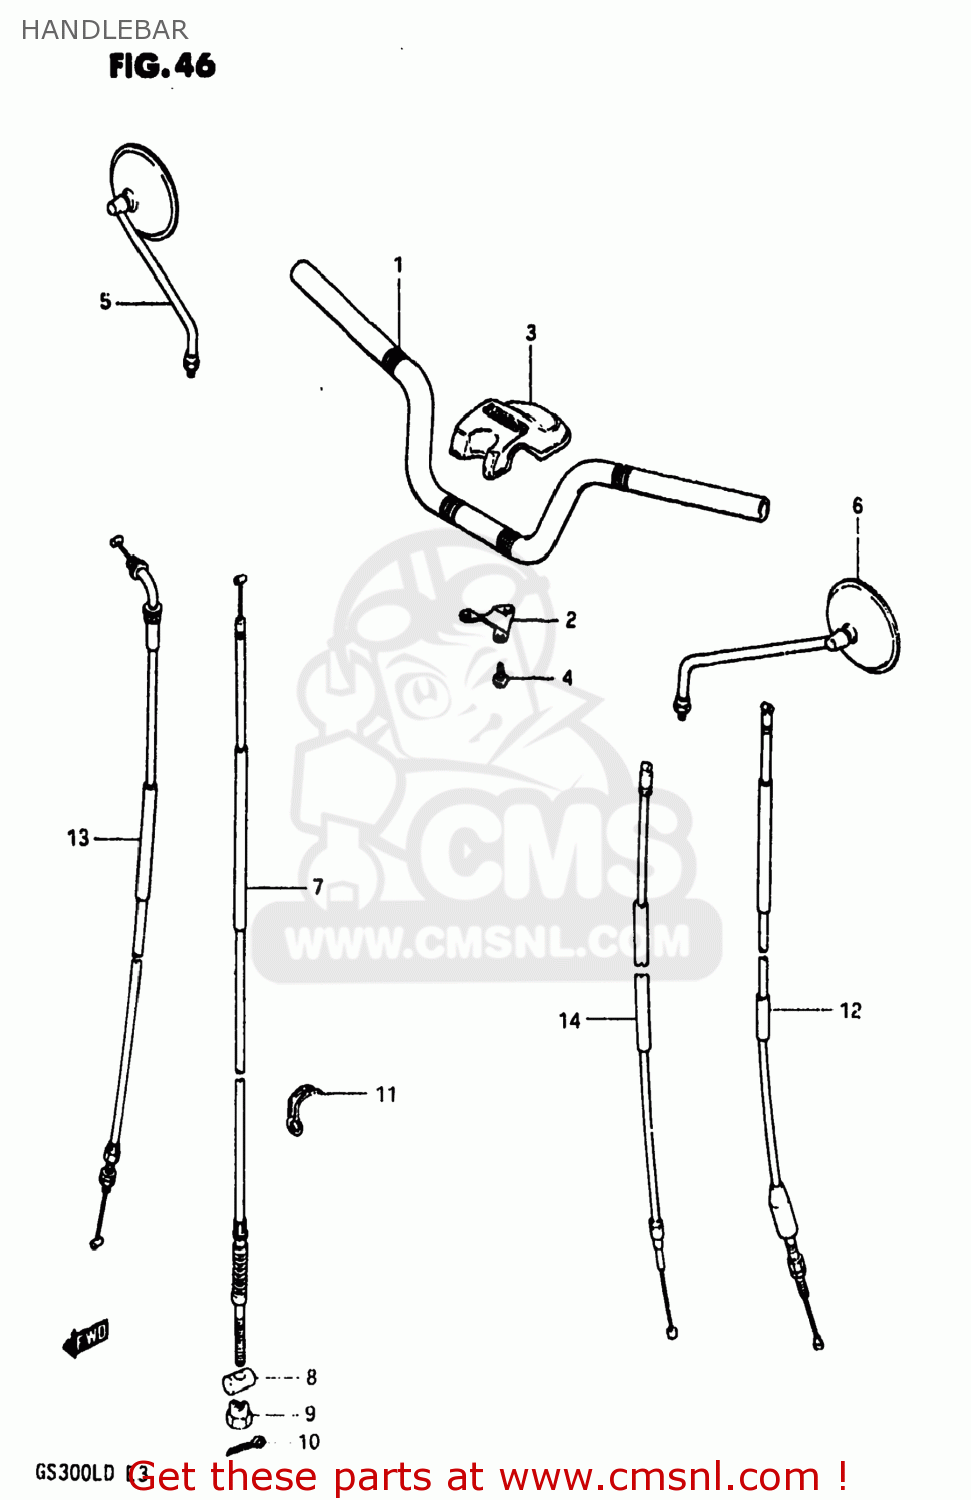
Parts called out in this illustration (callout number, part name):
1	HANDLEBAR
2	BRACKET,HEAD COVER
3	COVER,STEERING HEAD
4	SCREW
5	MIRROR ASSEMBLY,RIGHT
6	MIRROR ASSEMBLY,LEFT
7	CABLE,FR BRAKE
8	PIN
9	NUT (6MM)
10	PIN
11	LAMP ASSEMBLY
12	CABLE ASSEMBLY,CLUTCH
13	CABLE ASSEMBLY,THROTTLE
14	CABLE ASSEMBLY,STARTER
